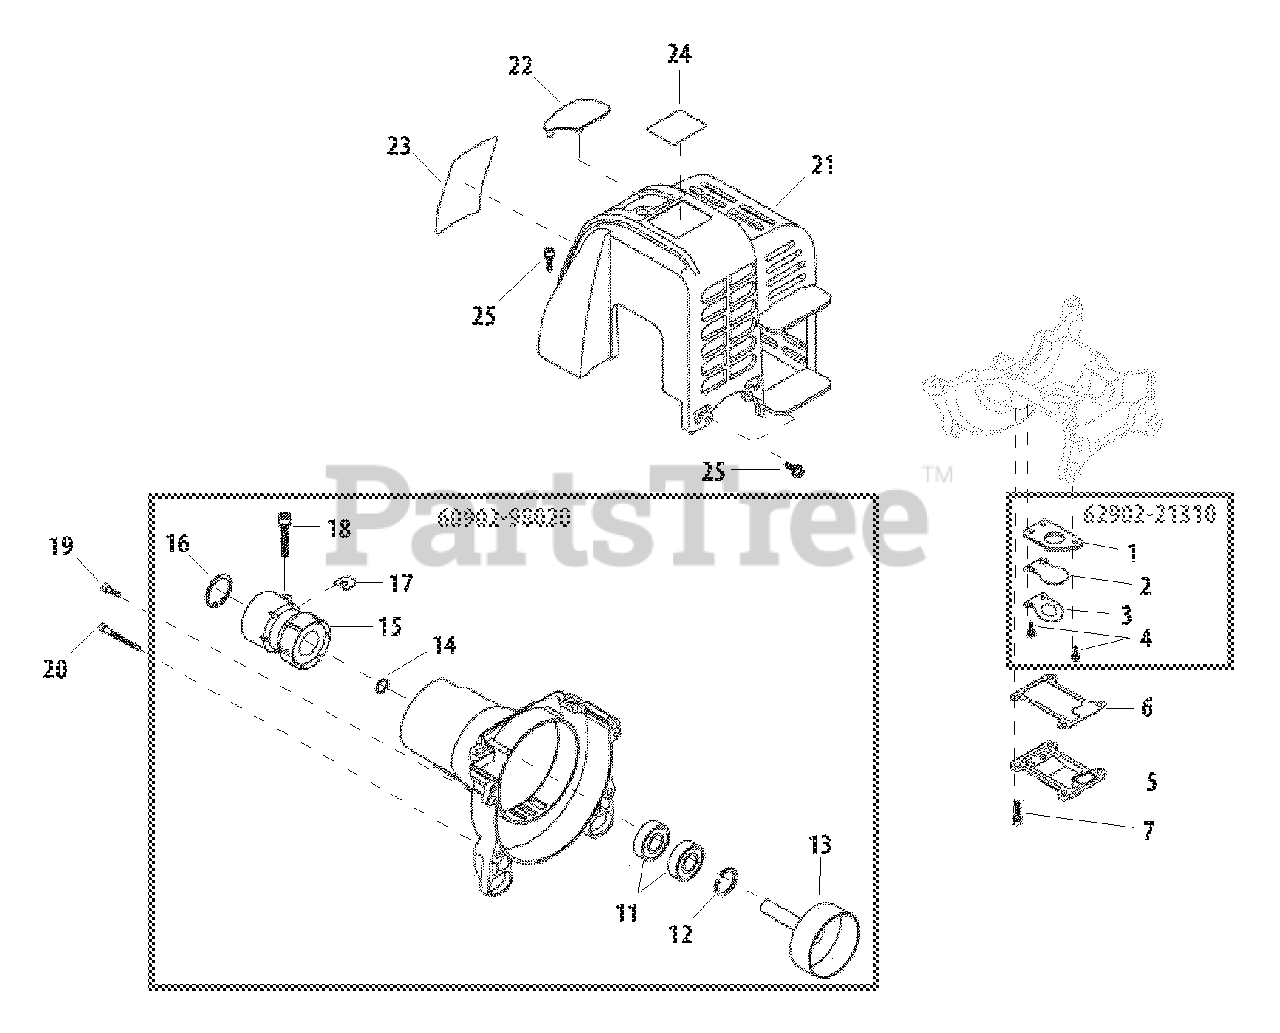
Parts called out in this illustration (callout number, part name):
1	PLATE, REED BACKING
2	VALVE, REED
3	STOP, REED VALVE
4	SCREW M3×10
5	COVER, REED VALVE
6	GASKET, REED VALVE
7	BOLT M4×12
11	BEARING, BALL 6000ZZ
12	RING, SNAP Ø26
13	DRUM, CLUTCH
14	RING, SNAP WR10
15	JOINT
16	RING, SNAP Ø40
17	D-WASHER
18	BOLT M5×22
19	BOLT 5×16
20	SCREW - 5×35
21	COVER, ENGINE
22	GROMMET
23	LABEL, C4 SHINDAIWA
24	LABEL - TRADE
25	BOLT M4×16
60902-98020	FAN CASE ASSY
62902-21310	REED VALVE ASSY
